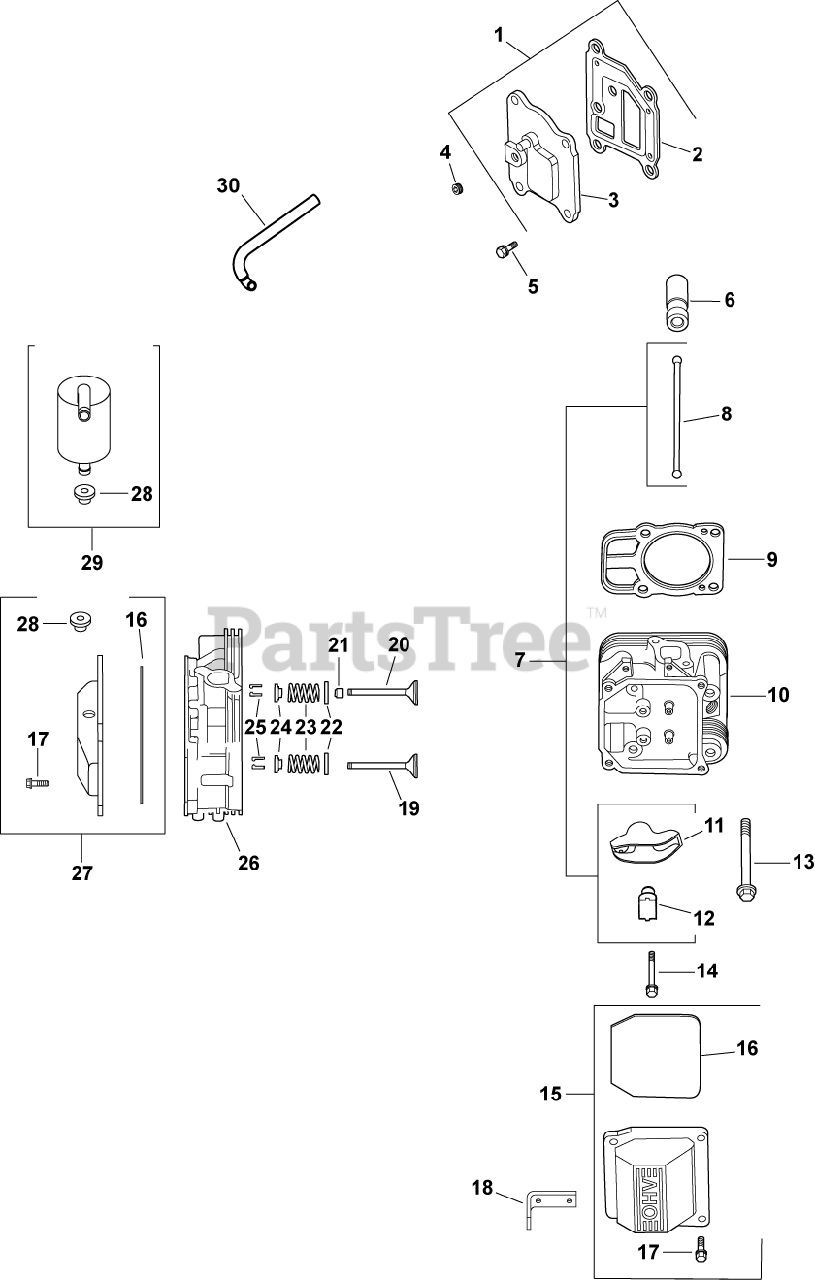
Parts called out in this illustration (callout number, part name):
1	KIT, BREATHER COVER W/GASKET
2	GASKET, BREATHER-USE 24 041 67-S
3	COVER, BREATHER -USE 24 096 125-S
4	PLUG, CTSK PIPE 1/8"
5	SCREW,FLG THD FRM M6X1.0X20-(#25086396S)
6	LIFTER, HYDRAULIC VALVE-USE 25 351 10-S
7	KIT, VALVE TRAIN
8	ROD, PUSH
9	KIT, GSKT CYL HD (C22-23 674CC)
10	KIT, #2 CYLINDER HEAD ASSEMBLY
11	ARM, ROCKER
12	PIVOT, CYLINDRICAL ROCKER ARM-USE 24 599
13	SCREW - USE 62 086 08-S
14	SCREW, FLG M6X1.0X34
15	KIT, VALVE COVER-PLAIN
16	O-RING (YELLOW) -USE 24 153 30-S
17	SCREW, FLG M6X1.0X30
18	STRAP, LIFTING-USE 25 445 03-S
19	VALVE, EXHAUST (STD) - USE 32 016 01-S
20	VALVE, INTAKE (STD)
21	SEAL, VALVE STEM - (#2503214S)
22	RETAINER, SPRING
23	SPRING, VALVE
24	RETAINER, VALVE SPRING - USE 25 173 28-S
25	KIT, RETAINER
26	KIT, #1 CYLINDER HEAD ASSEMBLY
27	KIT, VALVE COVER
28	GROMMET, RUBBER
29	KIT, BREATHR SEPARATR-(#24755241S)
30	HOSE, BREATHER-USE 24 326 93-S
2401602-S	VALVE, EXHAUST (.25)
2401702-S	VALVE, INTAKE (.25)
24755147-S	KIT, CYLINDER HEAD HARDWARE
